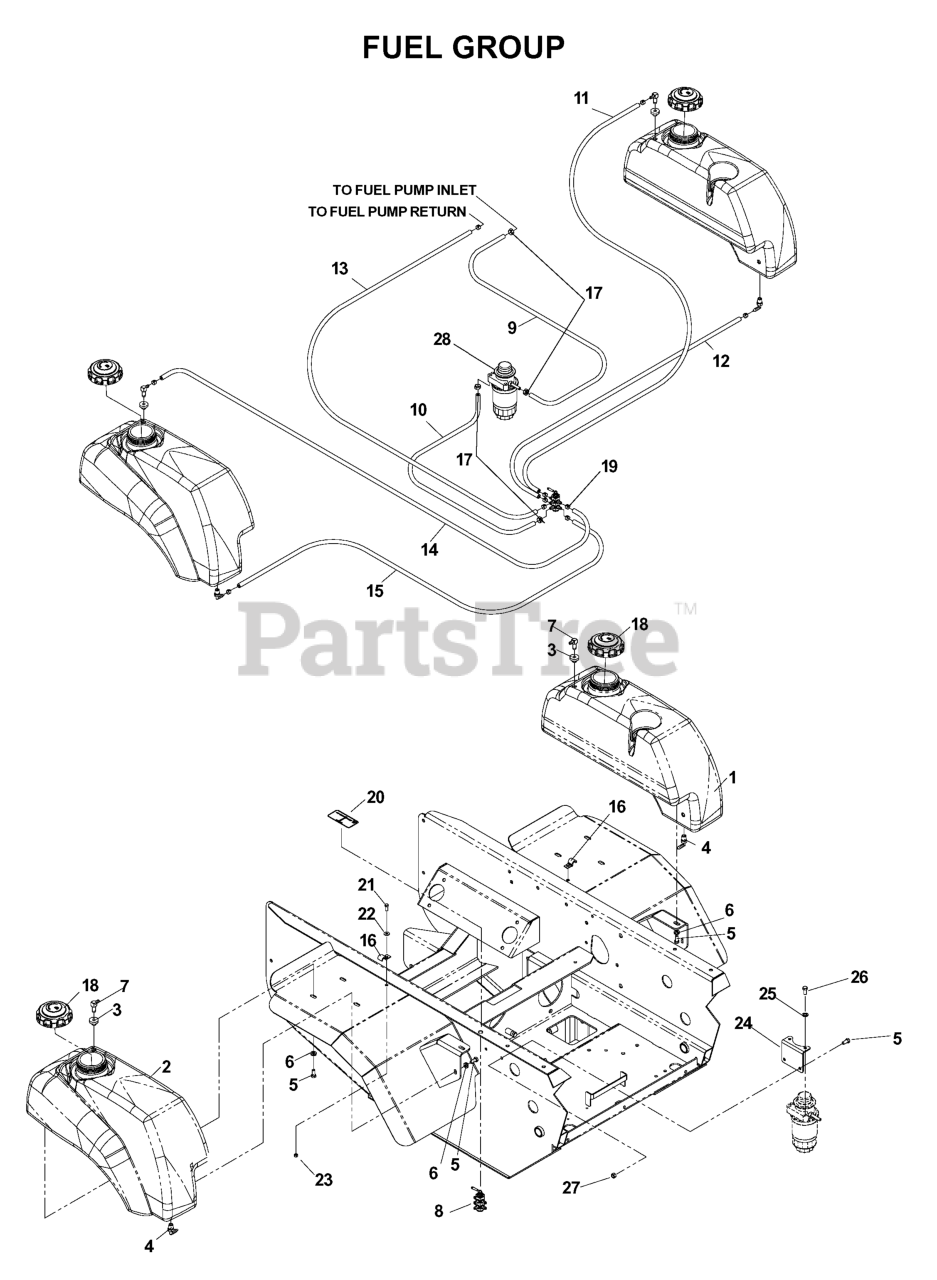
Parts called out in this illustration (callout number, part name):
1	FUEL TANK DIESEL LT
2	FUEL TANK DIESEL RT
3	RUBBER GROMMET
4	HOSE BARB 90 DEGREE
5	HCS 5/16C X 3/4
8	FUEL VALVE
9	FUEL LINE 38"
10	FUEL LINE 35"
11	FUEL LINE 79"
12	FUEL LINE 57"
13	FUEL LINE 54"
14	FUEL LINE 34"
15	FUEL LINE 13"
18	TANK CAP - DIESEL
19	HOSE CLAMP
20	FUEL VALVE DECAL
21	HCS 1/4C X 3/4 HCS
22	WASHER 1/4 FLAT
23	NUT.1/4-20.HEX.NYLOC.ZD
24	MOUNTING BRACKET
25	WASHER.LOCK.HVY.HLCL.SPR.5/16
27	NUT 5/16 NYLOC
28	FUEL FILTRATION SYSTEM
539106369	FUEL FILTRATION SYSTEM
